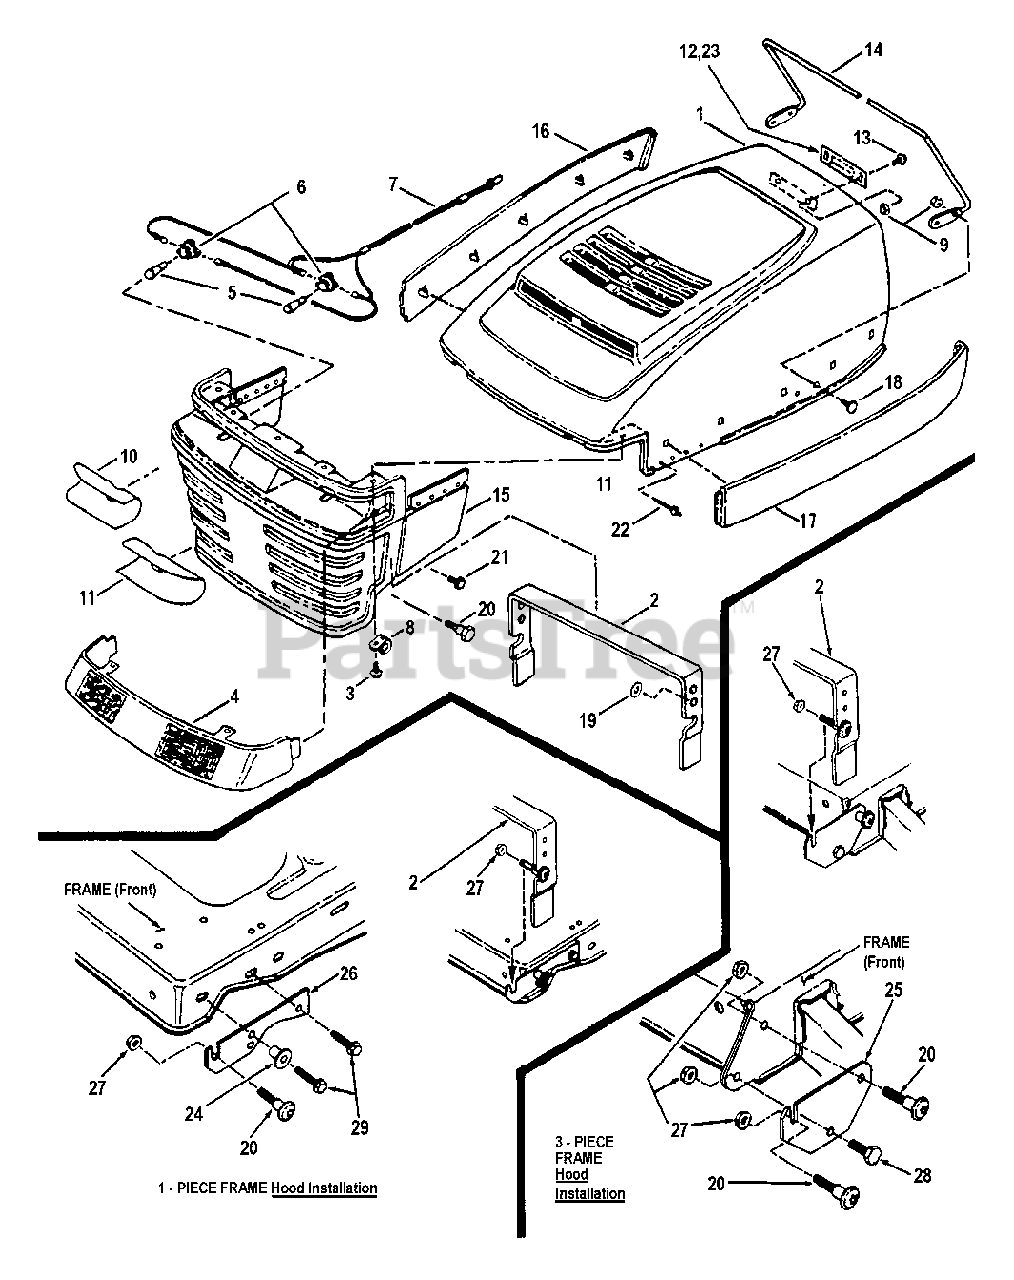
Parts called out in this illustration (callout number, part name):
1	HOOD, Mozart-Scoop-Red
2	BRACE, Hood Support/Stop
3	SCREW, M4.8 x 1.59 x 16.00mm Sems
4	LENS, Rippled-Sloped
5	LAMP, 1141
6	SOCKET, Headlight (Snap-in)
7	HARNESS, Headlight Wiring (M & G Sockets)
8	CLIP, "J" (open type)
9	NUT, 1/4-20 Hex Nyloc
10	DECAL, R.H. Lens/Reflector
11	DECAL, L.H. Lens/Reflector
12	LATCH, Spring
13	SCREW, 1/4-20 x 5/8" Truss Head Torx
14	ROD, Hood Support
15	GRILL, Sloped-Black
16	PANEL, R.H. Side-Black
17	PANEL, L.H. Side-Black
18	BOLT, 1/4-20 x 5/8" Flat Head Square Neck, Grade 2
19	RETAINER, 3/8" Bolt
20	BOLT, 3/8-16 Shoulder (2, plus 2 in hardware bag)
21	SCREW, 5/16-18 x 1/2" Hex Washer Self-tap
22	POP RIVET, 1/8 x 3/8"
23	CLIP, Hood Latch
24	BUSHING, Flange
25	BRACKET, Hood, Mozart LTH
26	BRACKET, Hood Pivot
27	NUT, 3/8-16 Hex Flange Lock
28	BOLT, 3/8-16 x 3/4" Hex Head, Grade 5
29	SCREW, 5/16-18 x 1-1/4" Hex Washer Self-tap
